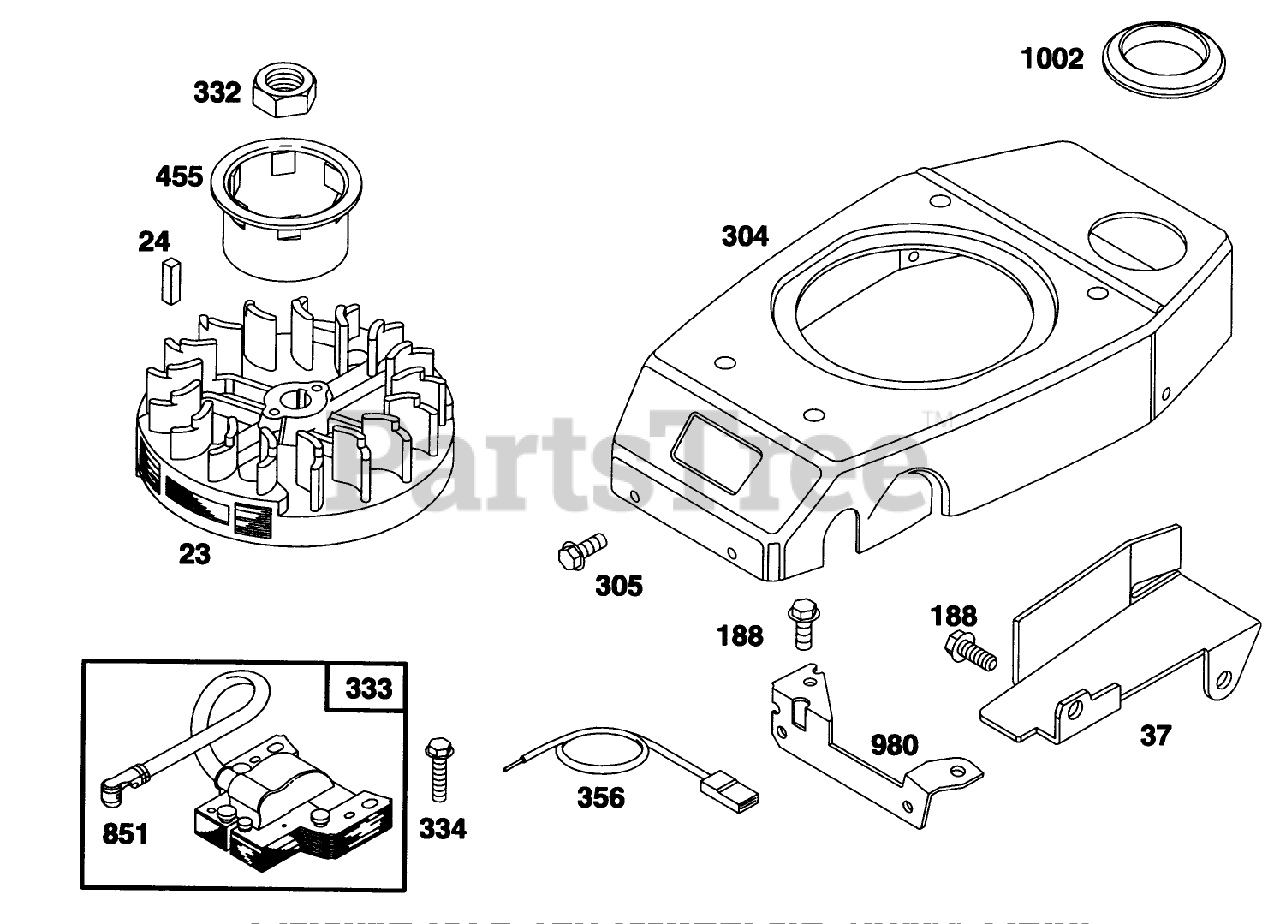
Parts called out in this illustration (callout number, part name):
24	KEY - FLYWHEEL
37	GUARD - FLYWHEEL
304	HOUSING - BLOWER
305	SCREW - HEX HEAD
332	NUT - HEXAGON
356	WIRE - GROUND
980	BRACKET-BLOWER HSG
